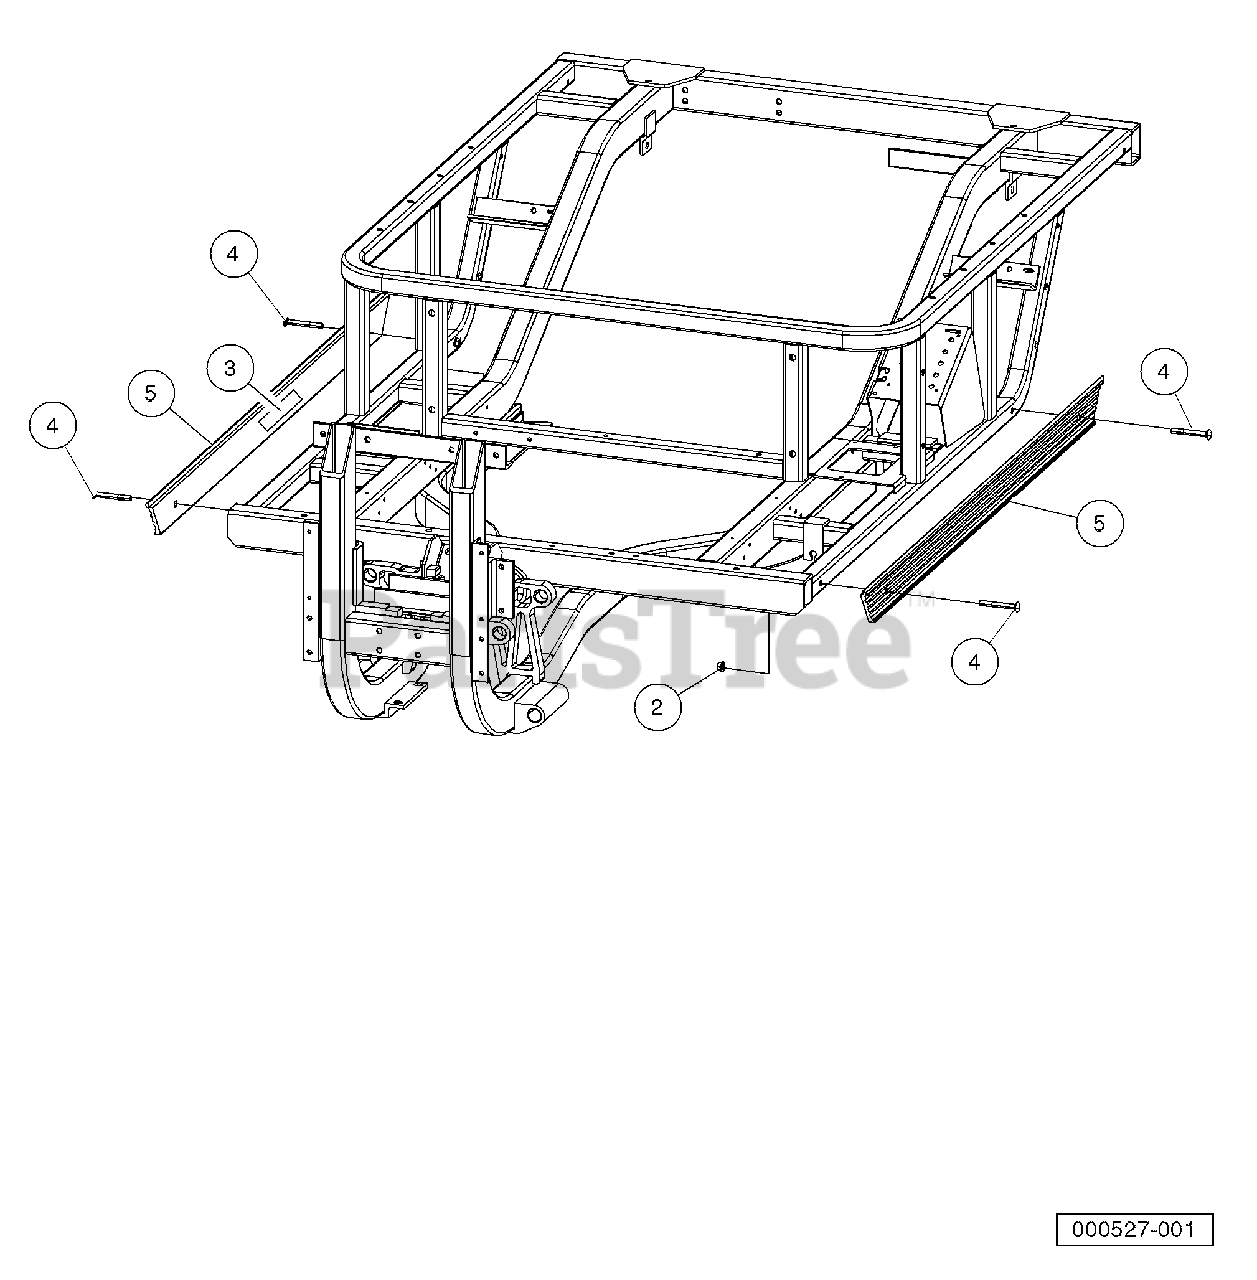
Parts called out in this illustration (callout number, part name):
1	Instl, Stringer, Black
2	Locknut, 3/8-16 Flanged Dimple
3	Tape, 3M VHB 4950
4	Bolt, 3/8-16 X 3, Carriage Blk
5	Stringer, Side, 1349.25, Black
